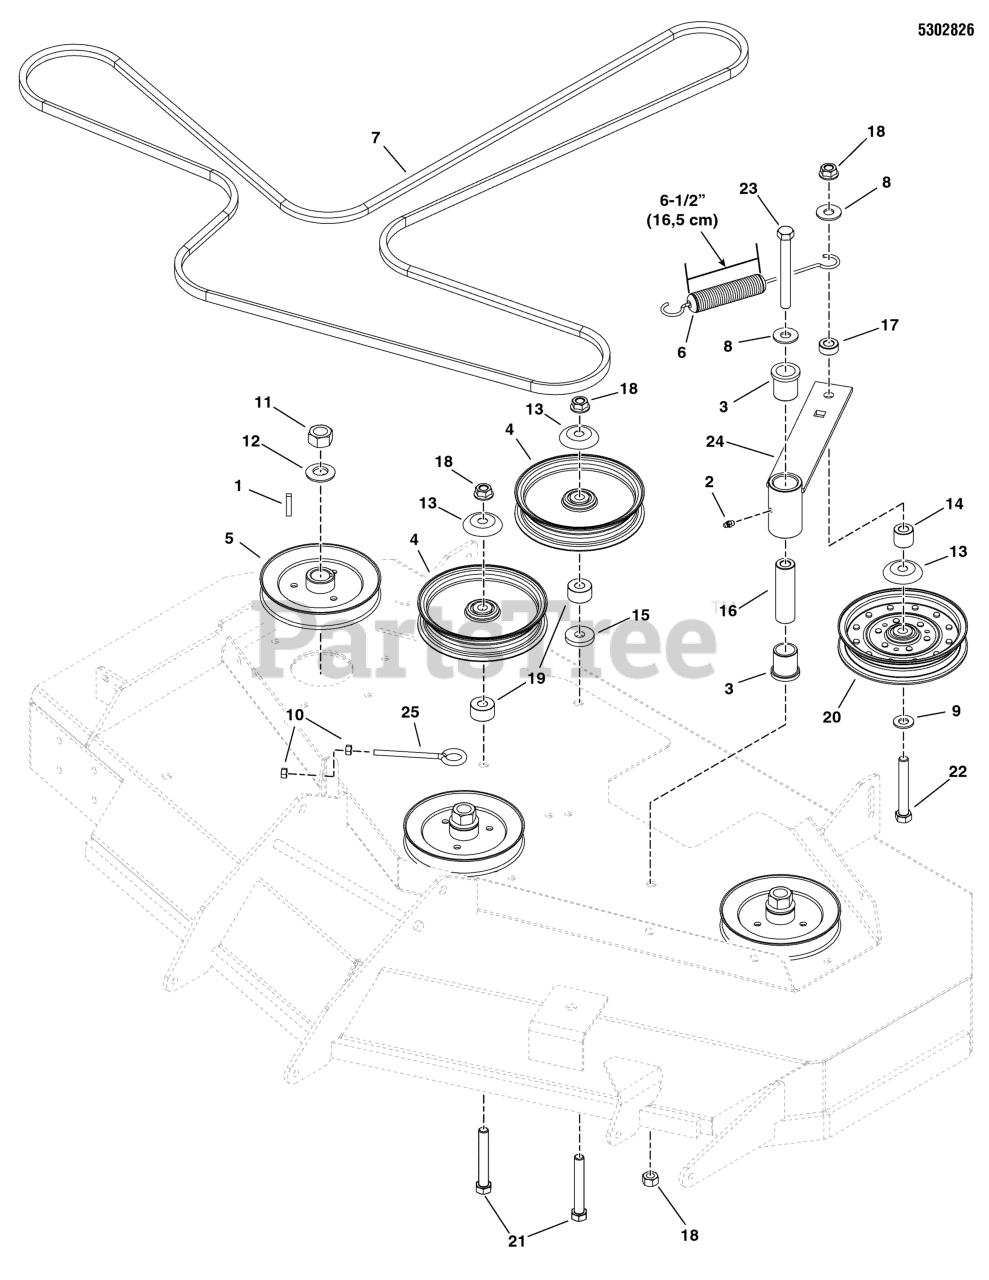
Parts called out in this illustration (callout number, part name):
1	KEY, 1/4 SQ. X 1-1/4
2	GREASE FITTING, 1/4-28 STRAIGHT
3	BUSHING, FLANGE
5	PULLEY, 5.926 OVER BALL
6	SPRING, EXTENSION, SWIVEL END
7	BELT, 5V, 163.40EL, LG ARAMID, WRPD, RC
8	WASHER, 1/2 USS
9	WASHER, 1/2 SAE
10	NUT, 3/8-16 HEX
11	NUT, 3/4-16 HEX
12	WASHER, 3/4 BELLEVILLE
13	SHIELD, PULLEY BEARING
14	SPACER, .52 X 1.00 X .88
15	WASHER, .53 X 1.50 X .25
16	SPACER, .52 X 1.00 X 3.50
17	SPACER, .52 X 1.00 X .44
18	NUT, Hex Flange, Nylock, 1/2-13
19	SPACER, .52 X 1.25 X .70
21	BOLT, 1/2-13 X 2-3/4 GD5 CZ
22	BOLT, 1/2-13 X 3-1/2, HEX HD, GD5, CZ (SV)
23	BOLT, 1/2-13 X 4-1/2 GD5
24	ASSM, IDLER ARM
25	EYE BOLT, 3/8-16 X 6, 3.0 THREAD
